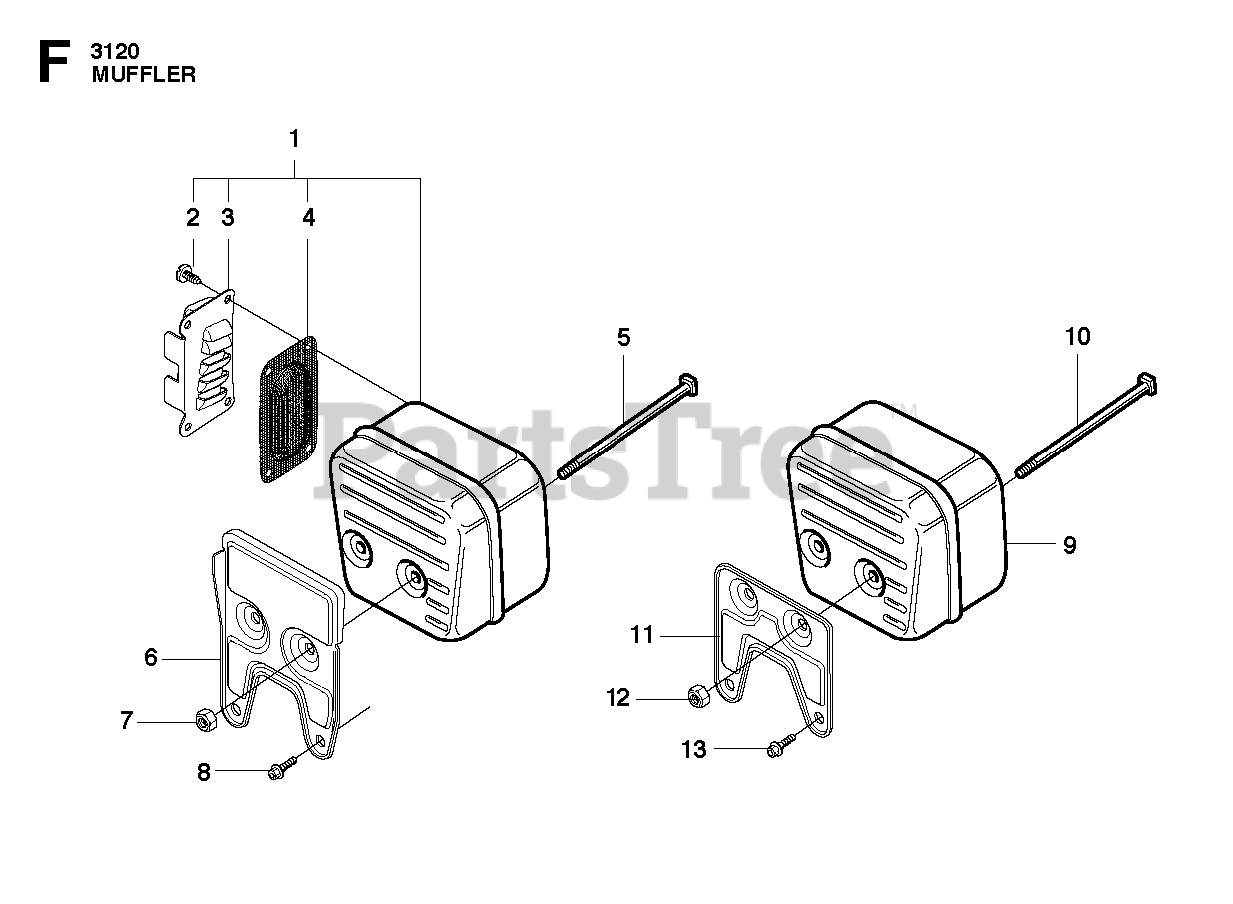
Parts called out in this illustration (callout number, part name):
1	MUFFLER
2	SCREW RXS B8X9.5
3	OUTLET
4	SCREEN
5	SCREW
6	SUPPORT
8	SCREW MC6S 5X12
8	SCREW MC6S 6X16
9	MUFFLER ASSY
10	SCREW
10	SCREW MC6S 6X16
11	SILENCER SUPPORT
13	SCREW MC6S 6X16
13	SCREW MC6S 5X12
